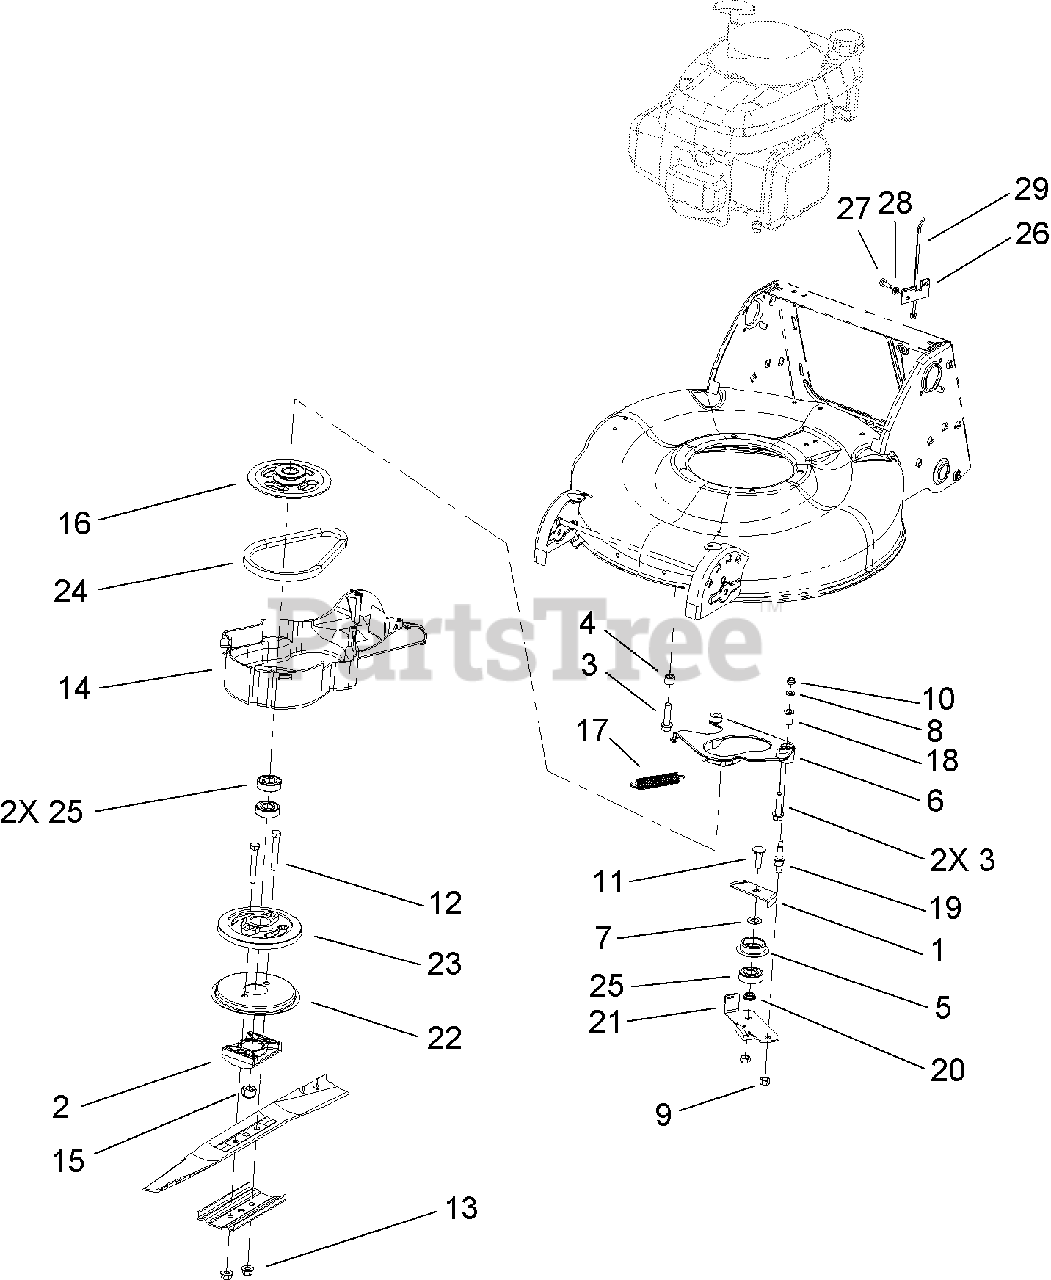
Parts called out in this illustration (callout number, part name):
1	PLATE-GUIDE
2	SUPPORT-BLADE
3	SCREW-HWH
4	TUBE-SPACER
5	RETAINER-BELT
6	PLATE-ANCHOR
8	WASHER-FLAT
10	NUT-LOCK, NI
11	SCREW-CARR
12	SCREW-HH
13	NUT-LOCK
14	COVER
16	PULLEY
17	SPRING-TENSION, BRAKE
19	BOLT-SHOULDER
20	SPACER-BEARING
21	BRAKE ARM ASM
22	DISC
23	DRUM
25	BEARING-BALL
26	CLAMP-CABLE,BBC
27	SCREW-HH
28	WASHER-LOCK
29	STRAP-TIE
